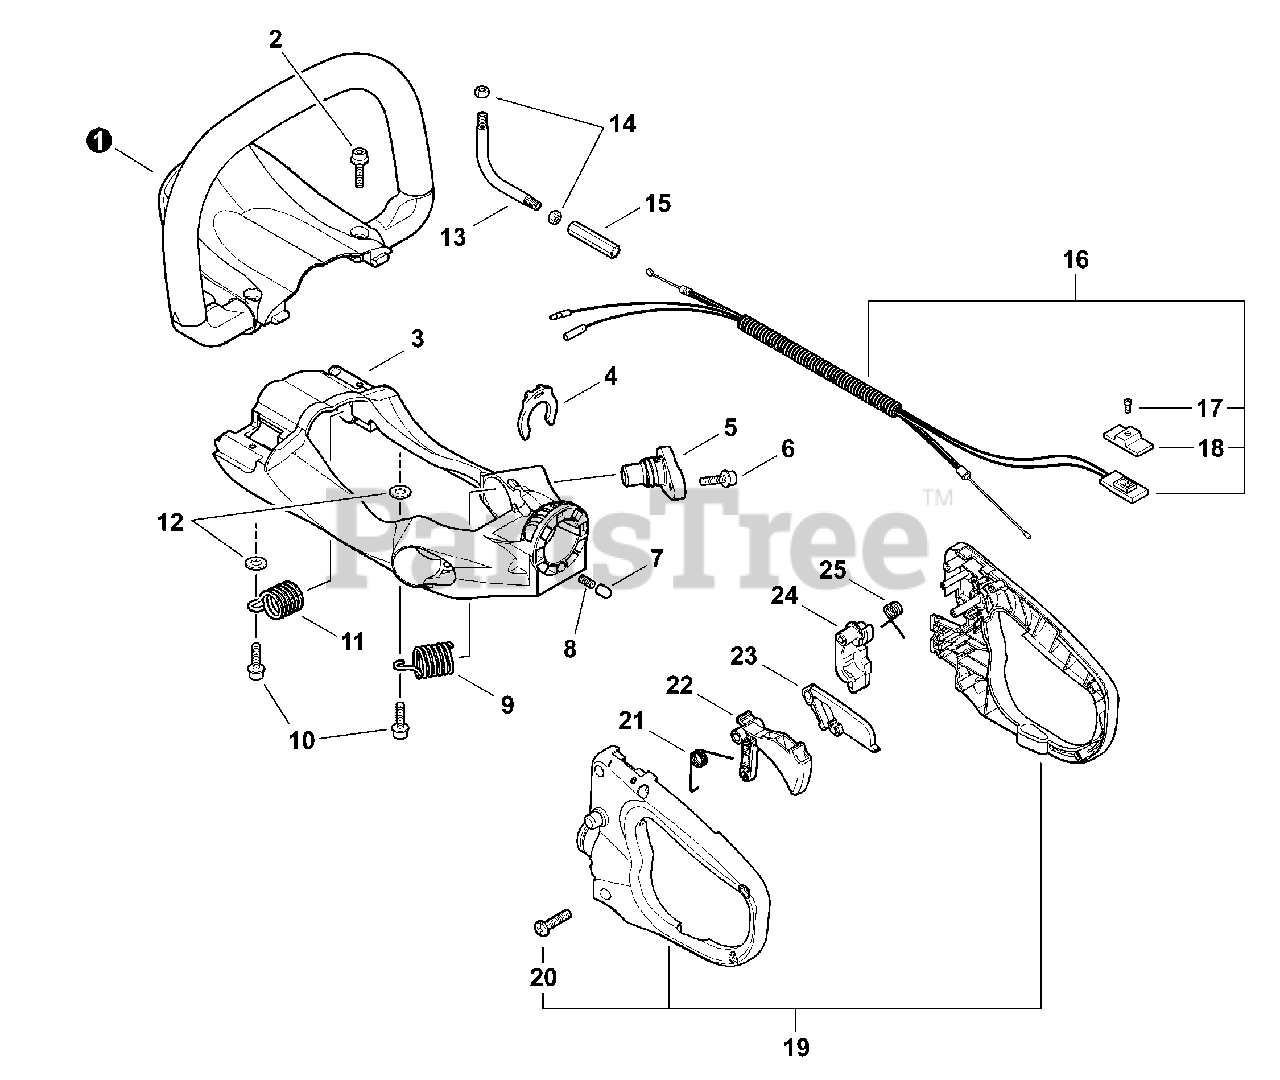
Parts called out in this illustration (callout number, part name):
1	HANDLE - FRONT
2	SCREW - 5×20
5	HOLDER, SPRING
6	SCREW - 5×20
10	SCREW - 5×16
12	WASHER - 5
13	TUBE, THROTTLE CABLE
15	CONNECTOR, THROTTLE CABLE
16	CONTROL CABLE ASSY
17	SCREW - 3×10
18	KNOB, SWITCH - ORANGE
19	REAR HANDLE SET
20	SCREW - 4×16
22	TRIGGER, THROTTLE
23	LOCKOUT, THROTTLE
24	LOCK, HANDLE
25	SPRING, HANDLE LOCK
